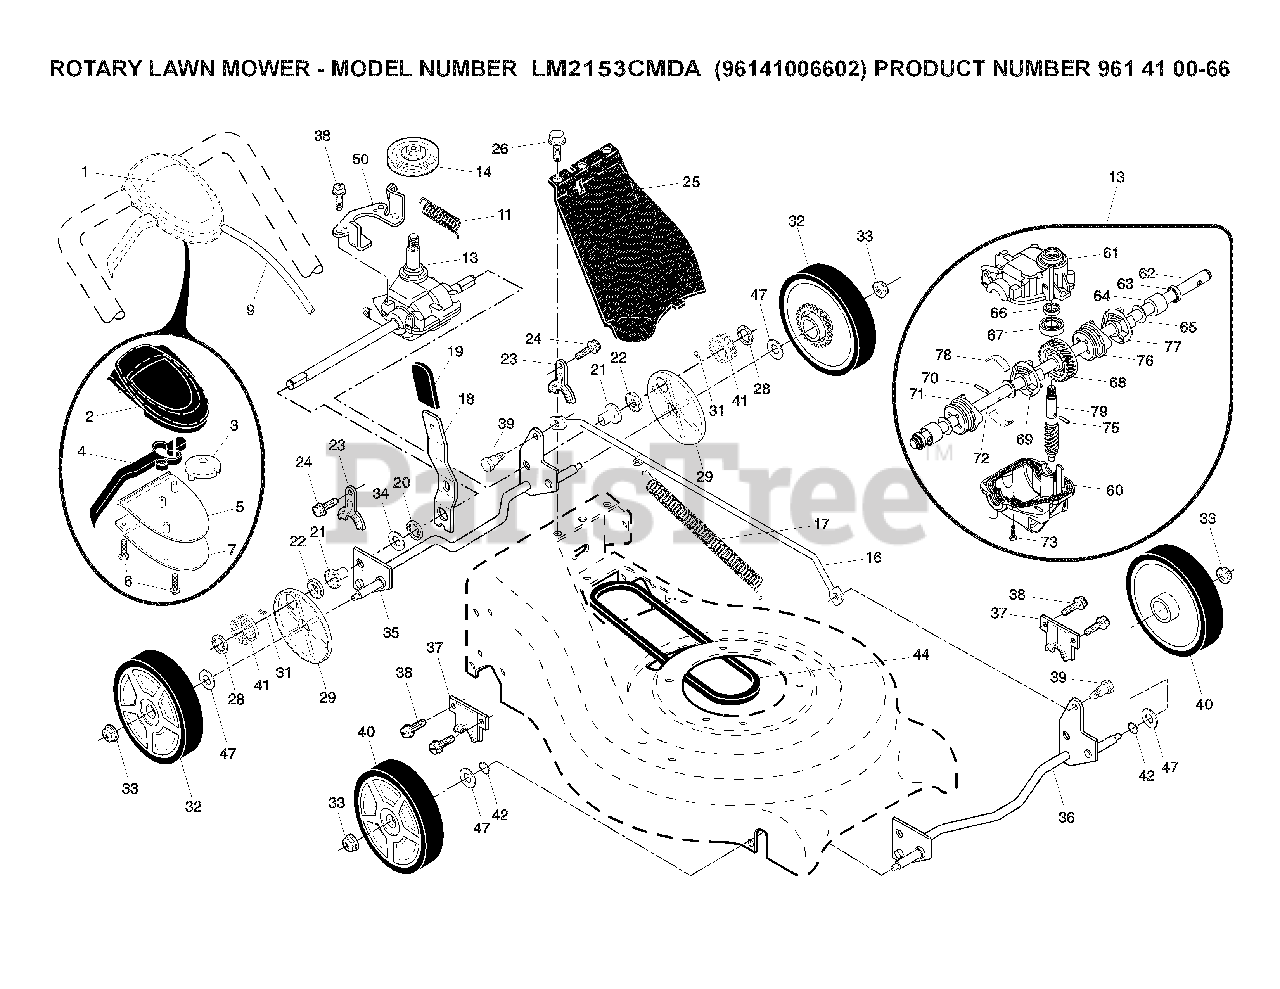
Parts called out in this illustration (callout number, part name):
2	COVER, TOP DRIVE CONTROL
3	PULLEY.CAM.DRIVE.CONTROL.EZ
5	COVER BOTTOM DRIVE CNTRL BLACK
6	SCREW, PHILLIPS HEAD 10 X 5/8
7	BRACKET.DRIVE.CONTROL.MOUNT
9	CABLE.ASSY.RGD.EZ.AUTO
13	TRANSMISSION.21.RWGD.AUTO.SP
14	PULLEY.1.PIECE
16	ROD.CONNECTING.SPT.BLACK
17	SPRING EXTENSION
18	SPRING.SELECTOR.SPT.21
19	KNOB, SELECTOR SPRING
21	BEARING SUPPORT
22	BEARING
23	BRACKET
28	E-RING 7/16 RE
29	COVER.DUST.WHEEL
31	PAWL, DRIVE
32	WHEEL.8X1.75.
33	NUT.HEX.FLANGE.3/8-16.LOCKNUT
35	SHAFT ASSY REAR
36	SHAFT ASSY, FRONT
37	RETAINER.FRONT.SHAFT
39	SHOULDER BOLT SEMI GIMLET PT.
40	FRONT WHEEL AND TIRE ASSY 8X2
41	PINIION.14.TOOTH.RGD
42	O-RING..070X.487.NEOPRENE
44	BELT.RGD.VS
47	WASHER FLUT
50	BELT KEEPER
60	CASE, LOWER
61	CASE UPPER
62	SHAFT OUTPUT LONG
63	SEAL.OUTPUT.SHAFT
66	SEAL INPUT SHAFT
68	GEAR 28 TEETH
69	FIXED DOG CLUTCH LH
70	PIN 7 33732
71	MOVEABLE DOG CLUTCH LH
72	SHAFT OUTPUT SHORT
75	PIN 3.50.337
76	FIXED DOG CLUTCH RH
77	MOVEABLE DOG CLUTCH RH
78	SPRING LEAF
79	SHAFT WORM
